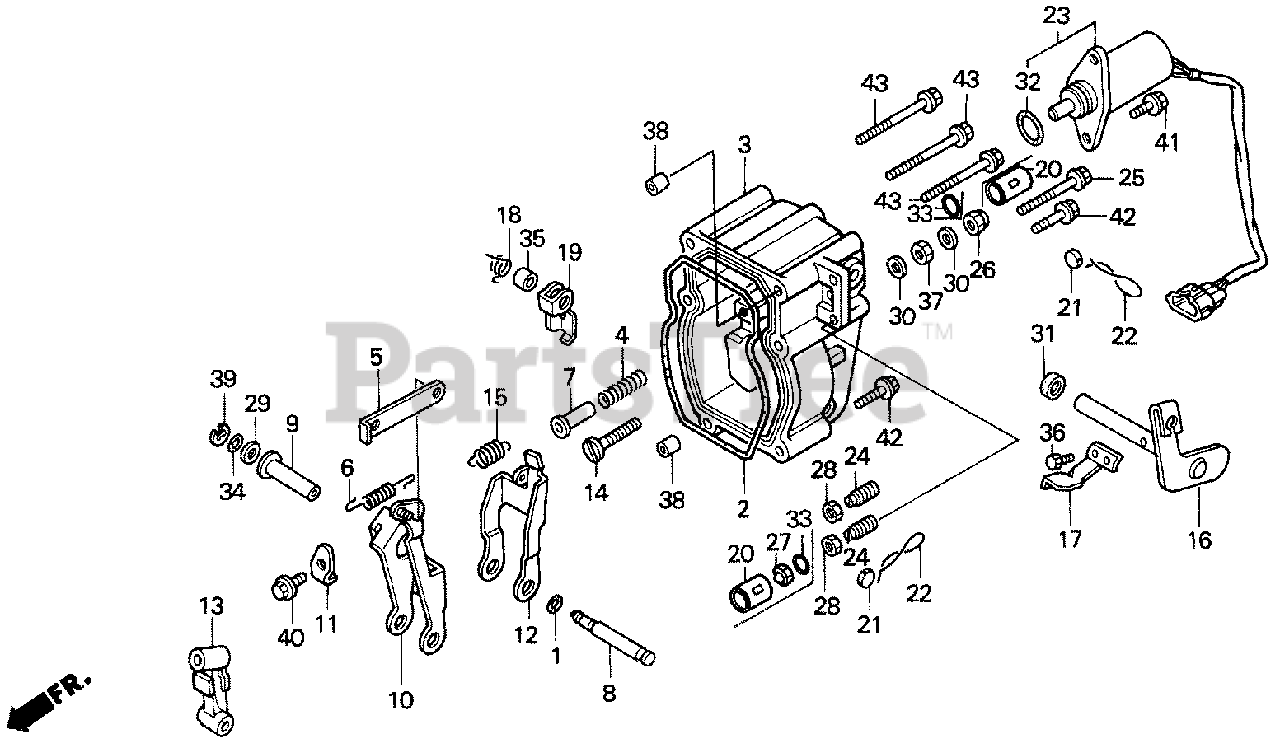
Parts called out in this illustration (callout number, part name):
1	O-RING (4.8X1.9)
2	GASKET, GOVERNOR COVER
3	COVER, GOVERNOR
4	SPRING, START
5	PLATE, CONTROL
6	SPRING, RACK RETURN
7	RETAINER, START SPRING
8	SHAFT, GOVERNOR ARM
9	COLLAR, GOVERNOR ARM SHAFT
10	ARM, RACK CONTROL
11	PLATE, STOPPER
12	ARM, GOVERNOR ADJUSTING
13	ARM, GOVERNOR
14	STOPPER, GOVERNOR ADJUSTING ARM
15	SPRING, GOVERNOR
16	LEVER, CONTROL
17	ARM, CONTROL
18	SPRING, STOPPER ARM RETURN
19	ARM, STOPPER
20	COVER, LOCK
23	SOLENOID ASSY., ENGINE STOP
24	SCREW, ADJUSTING
25	BOLT, FLANGE (6X85)
26	NUT, CAP (6MM)
27	NUT, CAP (6MM)
28	NUT, HEX. (6MM)
29	WASHER, PLAIN (6.5X16X2.6)
30	WASHER (6MM)
31	OIL SEAL (10X16X5)
32	O-RING A (15.5X1.5)
33	O-RING (7.8X1.9) (NOK)
34	O-RING (2.8X1.9) (P3)
35	COLLAR, STOPPER ARM
36	BOLT, HEX. (4X12)
37	NUT, HEX. (6MM)
38	PIN A, DOWEL (8X14)
39	E-RING (4MM)
40	BOLT, FLANGE (6X12)
41	BOLT, FLANGE (6X16)
42	BOLT, FLANGE (6X40)
43	BOLT, FLANGE (6X85)
